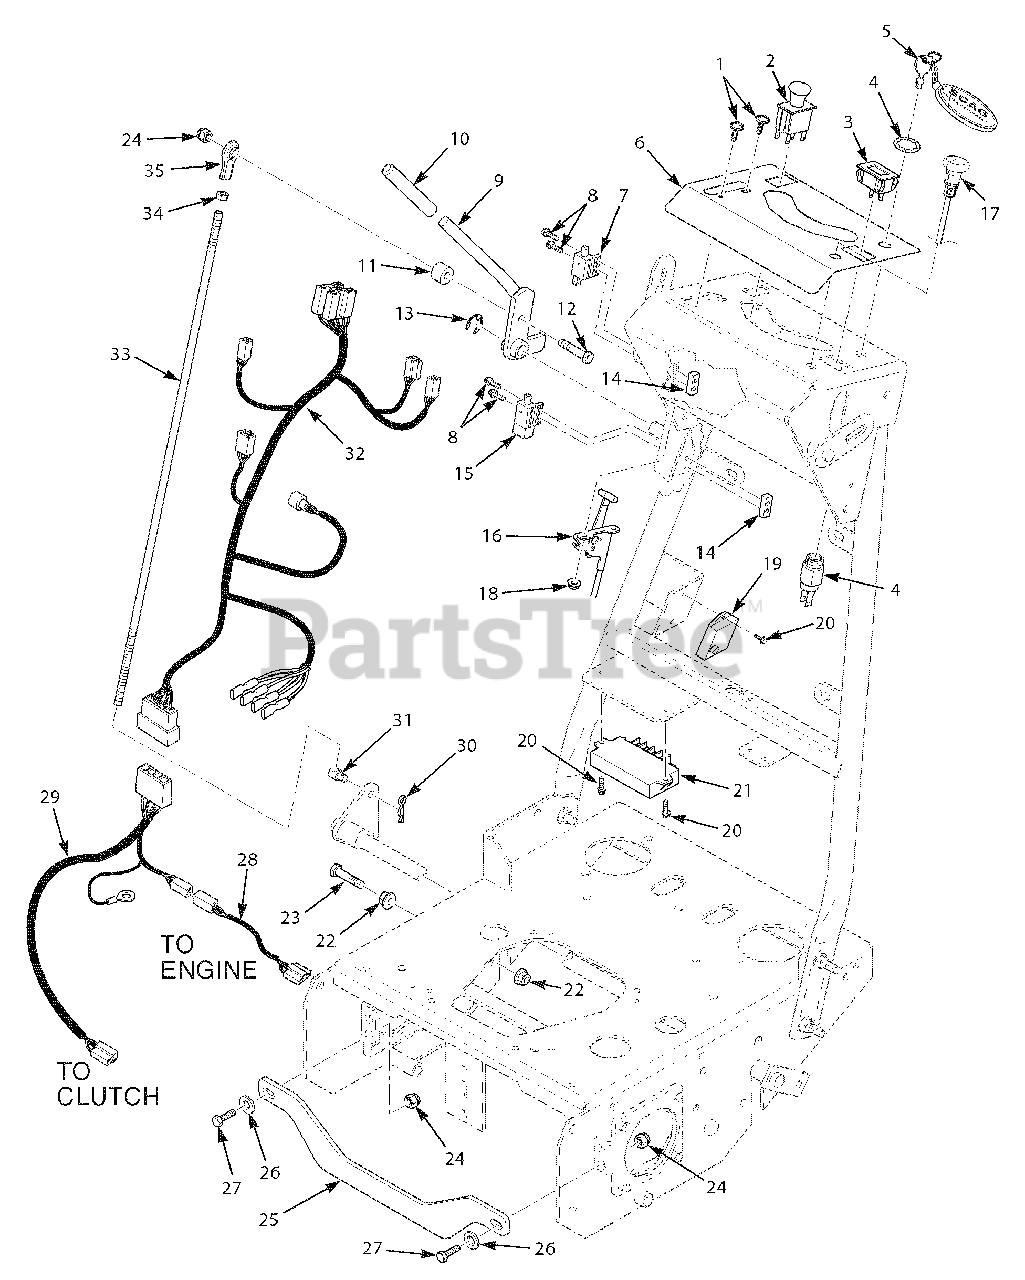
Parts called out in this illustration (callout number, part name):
1	Screw, Phillips #10-32 x 1/2"
2	Switch, PTO
3	Hour Meter
4	Key Switch
5	Key Fob w/Keys
6	Decal, Control Panel
7	Switch, N/C - Speed Control
8	Screw, Hex Head #10-32 x 3/4"
9	Lever, Brake
10	Grip, Brake
11	Spacer
12	Bolt, Hex Head 3/8-16 x 2"
13	Retaining Ring
14	Plate, Threaded
15	Switch, Interlock - Brake
16	Throttle Control
17	Choke Control
18	Nut, Serrated Flange #10-32
19	Voltage Regulator
20	Screw, Self Tapping
21	M o d ule, Senso Grip
22	N ut, Serrated Flange 3/8-16
23	Bolt, Hex Head 3/8-16 x 2-1/2"
24	Nut, Elastic Stop 3/8-16
25	Stiffener, SWZV
26	Flatwasher, 3/8-.391 x .938 x .105 HD
27	Bolt, Hex Head 3/8-16 x 1-1/4"
28	Engine Adapter Harness, Kawasaki
29	Wire Harness, Engine Deck Manual Start
30	Hair Pin Cotter, .094 x 1.62"
31	Swivel Joint
32	Wire Harness, Handle Bar Manual Start
33	Rod, Brake Lever
34	Nut, 3/8-24 UNF Jam
35	Rod End, 3/8-24 RH
